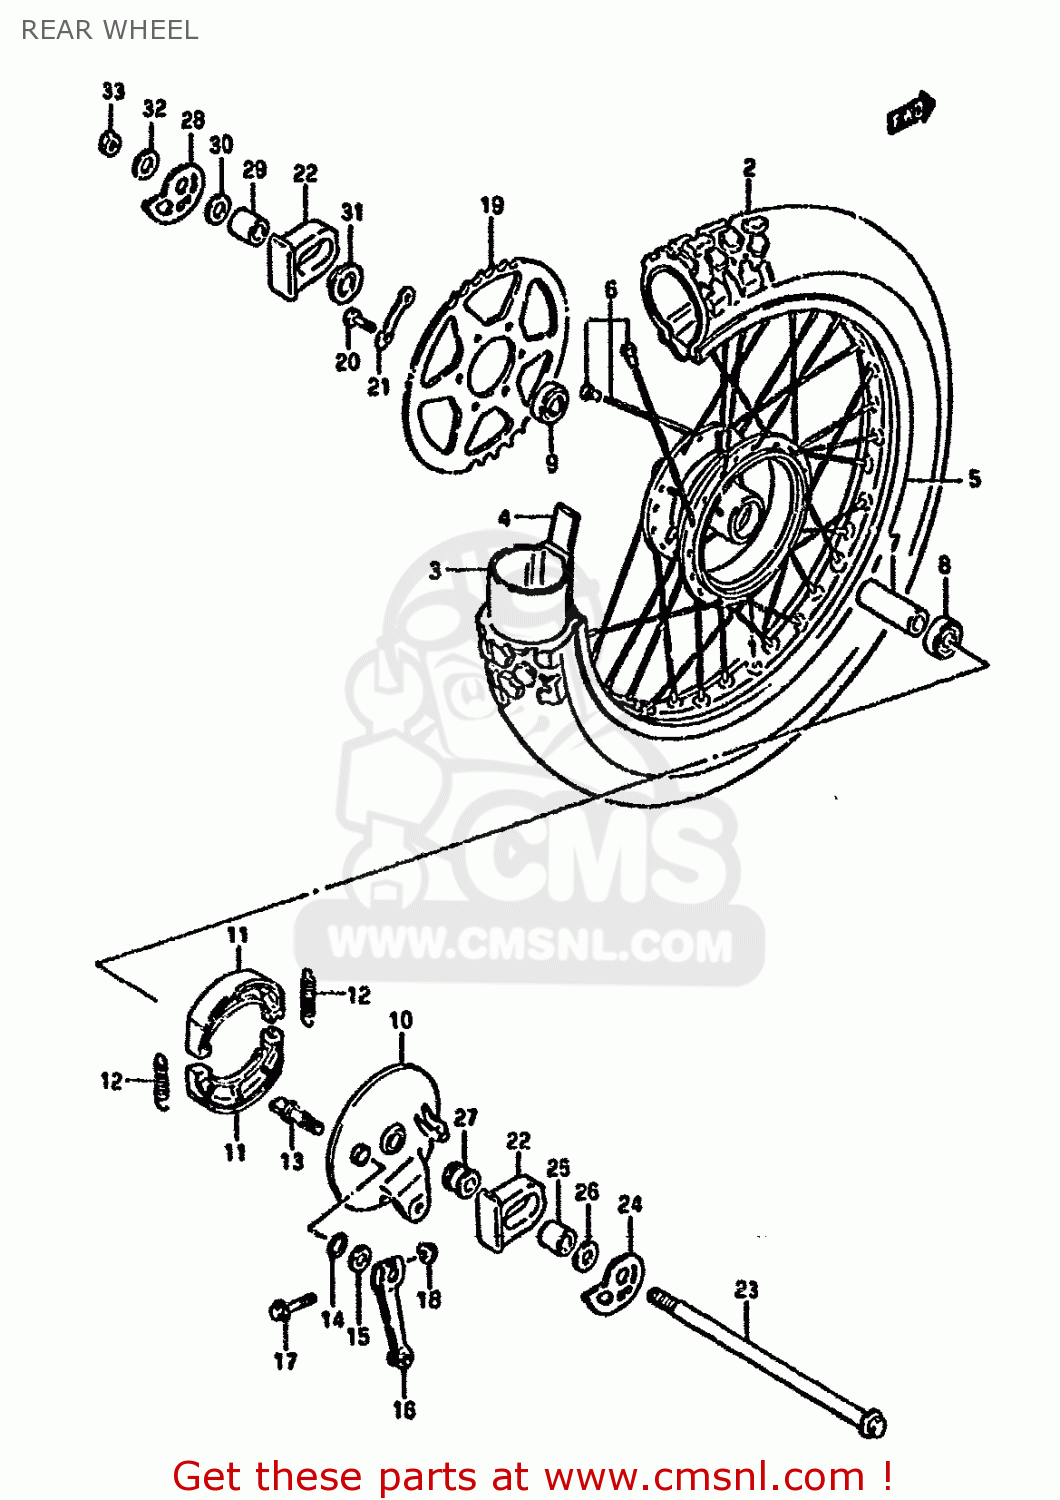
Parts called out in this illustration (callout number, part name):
1	HUB,REAR
2	TIRE
3	TUBE ASSEMBLY,WHEEL,INNER
4	PROTECTOR,WHEEL,INNER
5	RIM,REAR WHEEL
6	SPOKE SET,RR
7	SPACER(15.3X21.7X107.5)
8	BEARING
9	BEARING
10	PANEL,RR BRAKE ANCHOR
11	SHOE,BRAKE
12	SPRING(L:34)
13	CAM,FRONT BRAKE
14	O-RING (D:2.4 ID:13.8)
15	WASHER (14.5X22X1.6)
16	LEVER,RR BRAKE CAM
17	BOLT
18	NUT
19	SPROCKET,REAR
20	BOLT(8X30)
21	WASHER
22	CAP,RR SWINGING ARM
23	AXLE,REAR
24	ADJUSTER,CHAIN,R
25	SPACER,CHAIN ADJUSTER
26	WASHER(15.5X26X2.3)
27	SPACER,RR AXLE,R
28	ADJUSTER,CHAIN,L
29	SPACER,CHAIN ADJUSTER
30	WASHER(15.5X26X2.3)
31	SPACER,RR AXLE,L
32	WASHER
33	NUT 14MM
